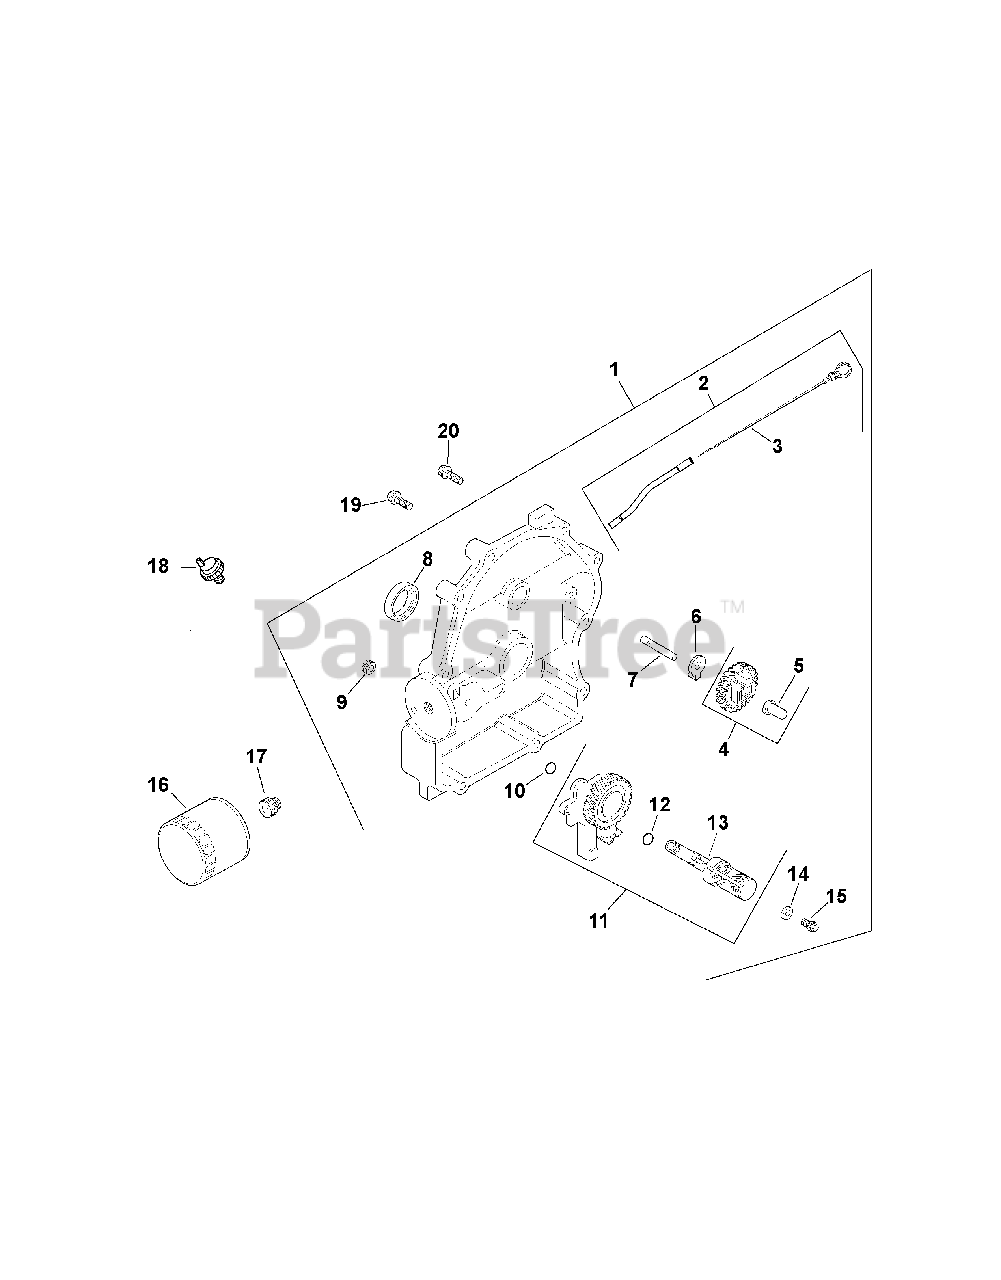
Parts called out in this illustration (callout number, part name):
1	Plate, closure assembly (Includes 2-15)
2	Kit, tube w/dipstick (Includes 3)
4	Kit, governor gear (Includes 5)
5	Pin, governor regulating
7	Shaft, governor gear
8	Seal, oil (PTO end)
9	Plug, pipe 1/8" (2)
11	Oil pump assembly (Includes 12,13)
12	O-Ring, oil pick-up
13	Pick-up, oil
14	Washer, plain 6 mm (2)
15	Screw, hex. flange M6x1 0x25 (2)
16	Filter, oil
17	Nipple, oil filter
18	Switch, pressure
19	Screw, hex. flange M8x1.25x45 (9)
20	Screw, hex. flange M8x1.25x45
